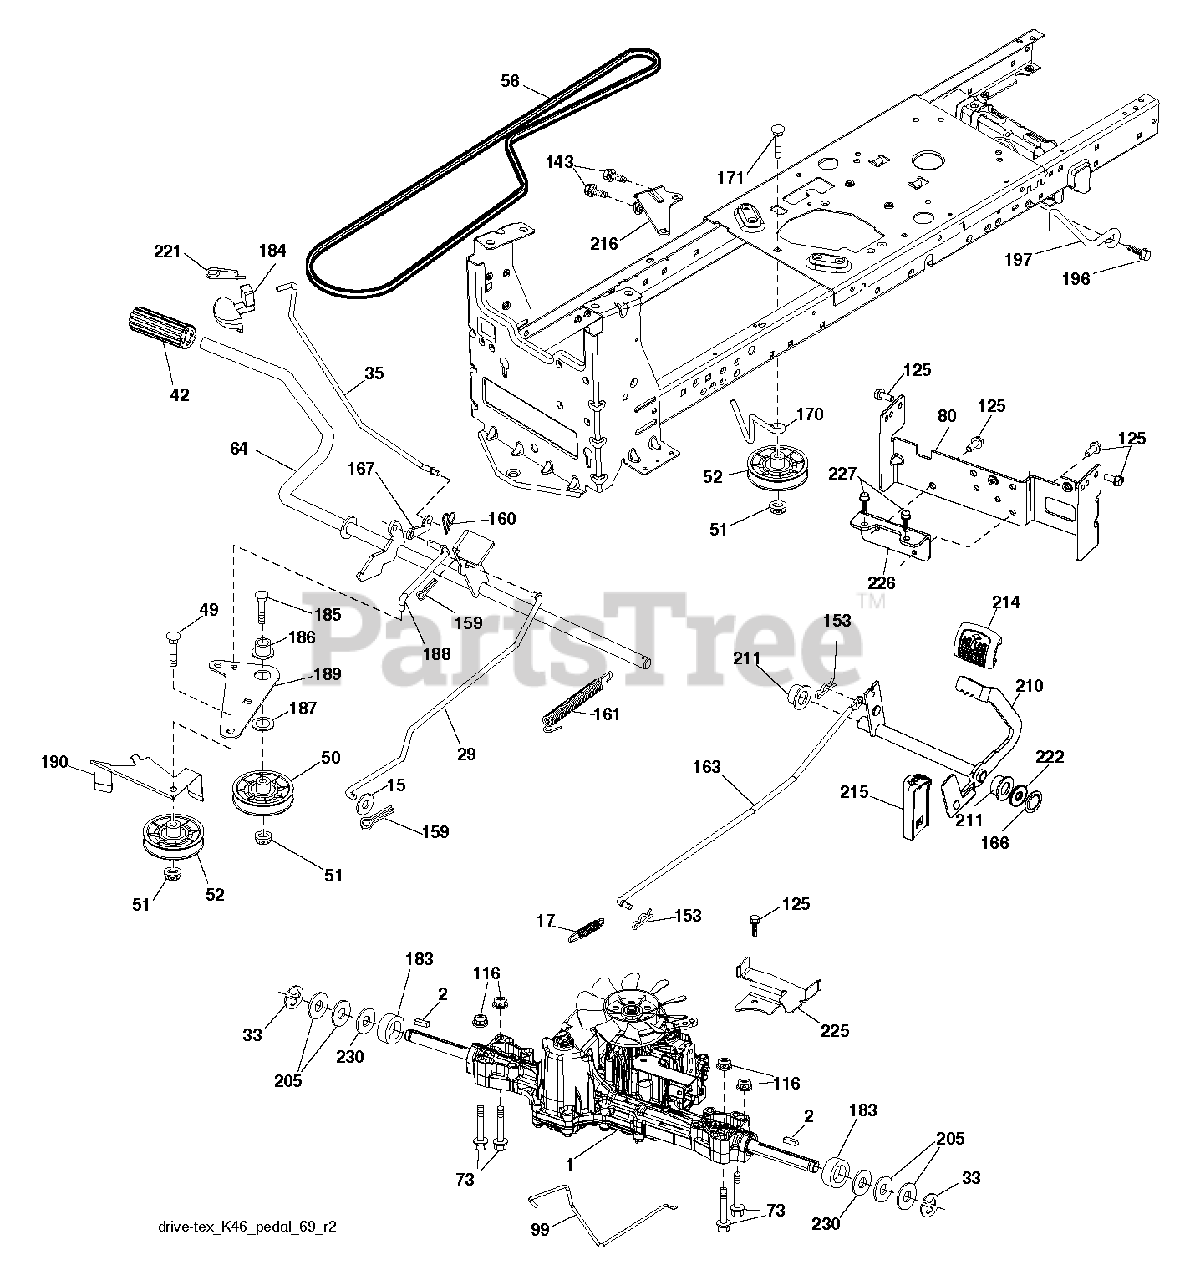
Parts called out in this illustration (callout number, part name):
2	SQUARE KEY
15	WASHER
17	SPRING.BRAKE.K46.GREEN
29	ROD.BRAKE.K46
35	ROD.CNTRL.PARK.PREDATOR.LT.TEX
42	PEDAL COVER T
50	IDLER.FLAT.910.OFFSET
51	NUT LOCK FLG 3/8-16 UNC
52	IDLER.V-GROOVE.910.OFFSET
56	V-BELT.MOWER.92.40.42/K46
64	SHAFT.ASM.PEDAL.BRK.CNTR
80	STRAP.TORQUE.K46.K57R.TT
99	ROD.SPRING.BYPASS.K46.LT.Z
116	NUT LOCK HEX FLANGE 5/16-18
125	SCREW
143	SCREW LT
153	RETAINER M
159	COTTER PIN
160	RETAINER CLIP
161	SPRING, RETURN LT
163	ROD.CONTROL.K57R.K46
166	NUT.PUSH.625
167	LATCH.BRAKE.SPRING
170	KEEPER.V-IDLER.CENTER.
183	SPACER AXLE
184	HANDLE.PARKING.BRK.PRED.LT.RED
186	SPACER.RETAINER
187	WASHER 12/32X2X10GA
188	RP LINK.CLUTCH.GROUND.DRIVE
189	BELLCRANK.GROUND.DRIVE.TEX.
190	KEEPER.BELLCRANK.DRIVE
196	SCREW 3/8-16X1
197	LINK.CLUTCH.ANIT-ROTAT
210	ROCKER.ASM.PEDAL.CONTR
211	BEARING.NYLON
214	PEDAL.FORWARD.PAD.TEX
215	PEDAL.REVERSE.TEX.GT.4
216	BRACKET.PULLEY.IDLER.W/TEX
221	RETAINER.SPRING.CLIP.H
222	WASHER 21/32 X 1-1/4 X 10 GA.
225	KEEPER.BELT.TRANSAXLE.K46
226	BRACKET.MOUNT.TORQUE.K46.TLT
227	SCREW
230	WASHER.HARDENED
